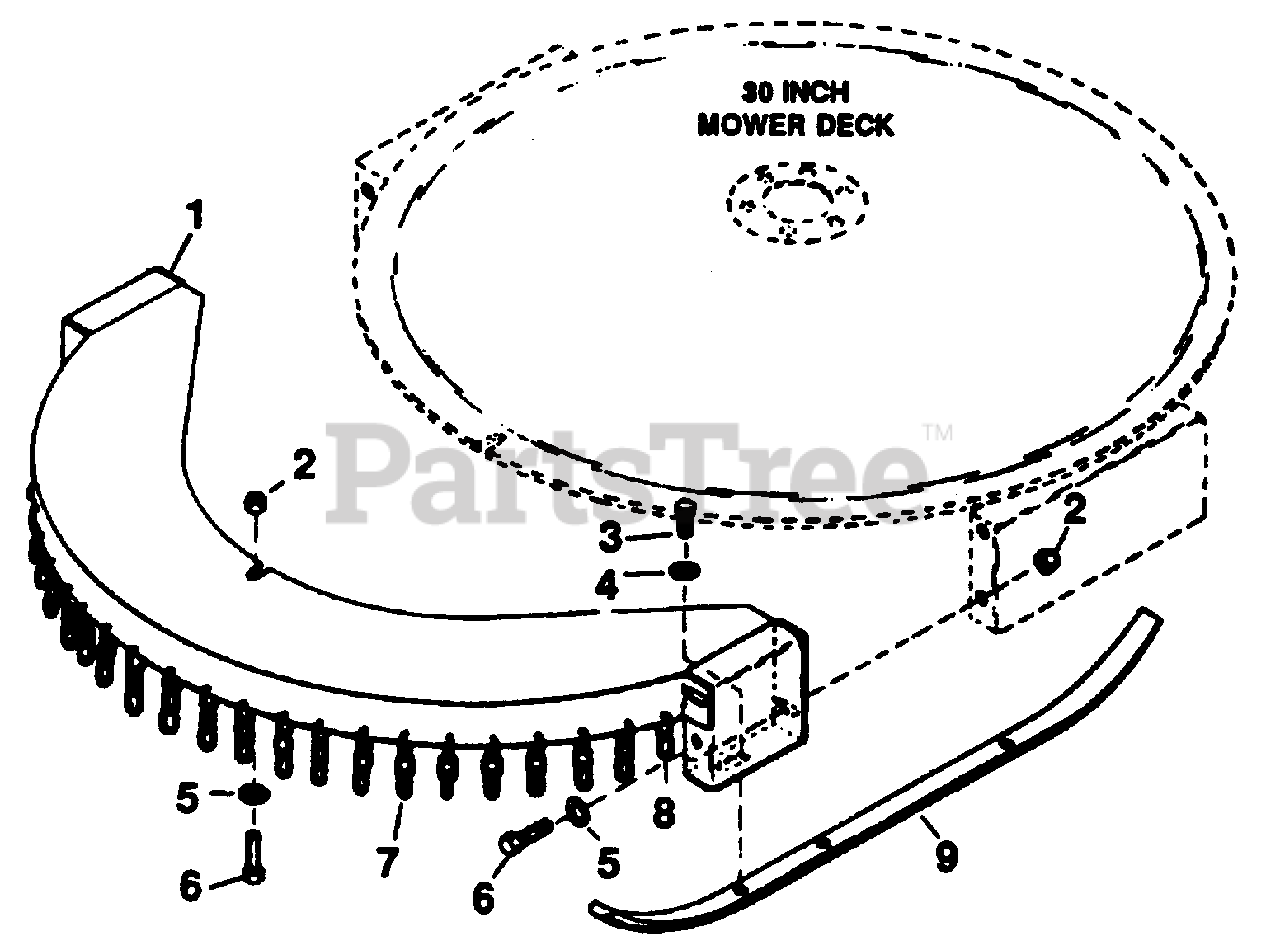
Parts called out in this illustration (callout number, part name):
1	Weldment, Chain Guard
2	Nut, Lock 5/16-24
3	Bolt, Hex 5/16-24x.625
4	Washer, Lock 5/16 Internal Tooth
5	Washer, Flat .406x.812x.065
6	Bolt, Hex 5/16-24x.875
7	Chain, 3 Link
8	Chain, 2 Link
9	Skid, Chain Guard
